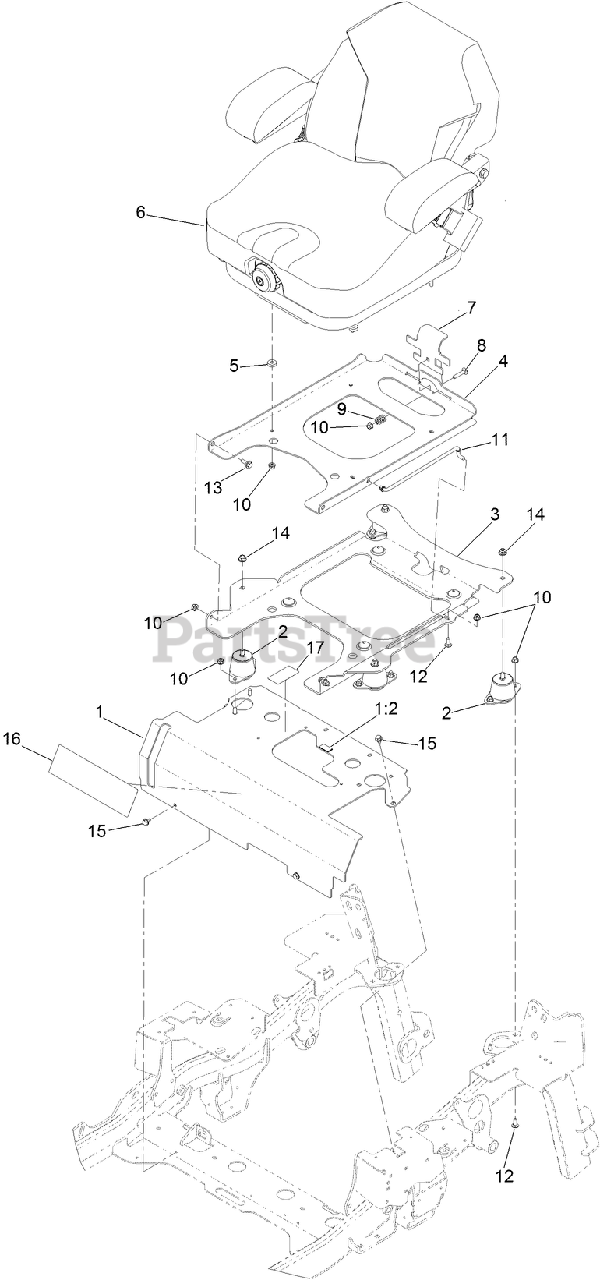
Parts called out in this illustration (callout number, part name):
1	SEAT MOUNT ASM
1:2	DECAL-WARNING
2	ISOLATOR-SEAT
3	PLATE-SUPPORT, TILT SEAT
4	PLATE-FRAME, SEAT
7	PLATE, SEAT LATCH
8	BOLT-CARR
9	SPRING-COMPRESSION
10	NUT-HF, NI
11	ROD-PROP
12	SCREW-CARR
13	SCREW-SHOULDER
14	NUT-HF, NI
15	SCREW
17	DECAL-FLUID, TRANSMISSION
